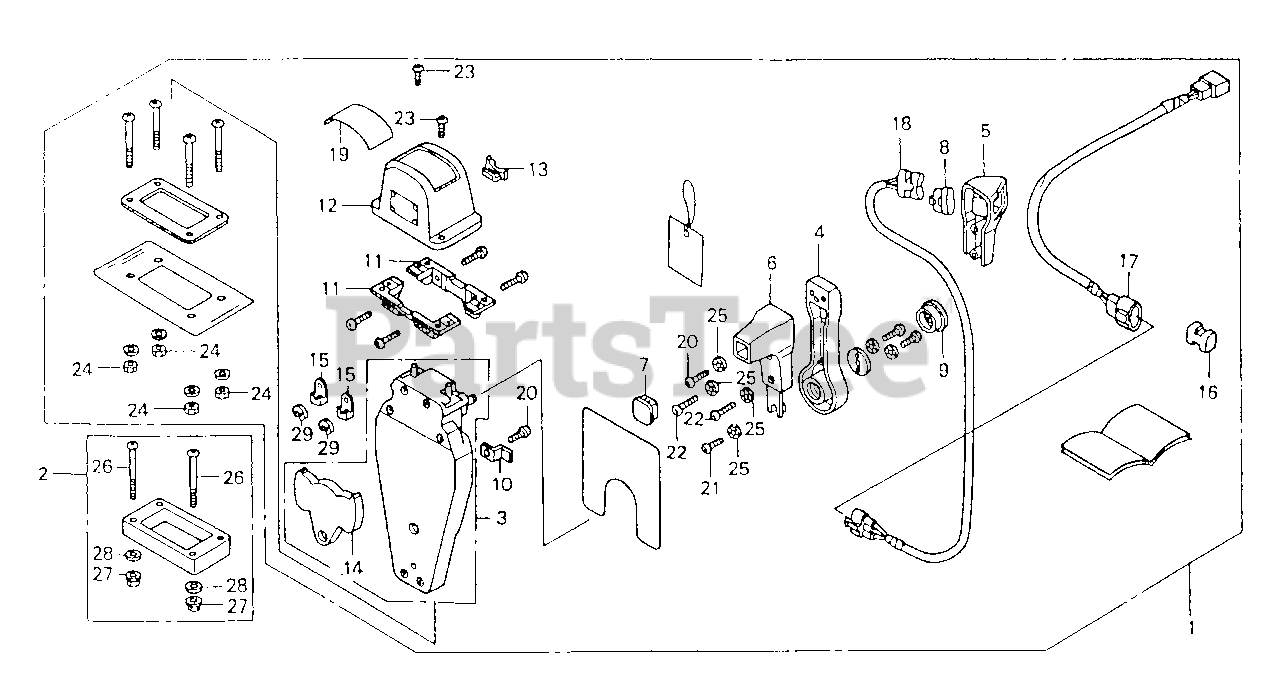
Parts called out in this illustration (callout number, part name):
1	BOX KIT, L. REMOTE CONTROL (TOP MOUNT SINGLE)
2	SPACER, TOP SINGLE
3	HOUSING ASSY., R. (INNER) (TOP MOUNT)
4	HANDLE, REMOTE CONTROL
5	COVER, R. GRIP
6	GRIP, REMOTE CONTROL HANDLE
7	CAP, GRIP
8	CAP, SWITCH
9	BUTTON, THROTTLE
10	PLATE, CABLE CLAMP
11	BRACKET, REMOTE CONTROL HOUSING
12	HOUSING, REMOTE CONTROL BOX
13	HOUSING, LEAD
14	PLATE, DWELL
15	CABLE, TERMINAL
16	SPACER, CABLE CLAMP
17	SUB-HARNESS B ASSY., POWER TRIM-TILT
18	SWITCH ASSY., POWER TRIM-TILT
19	MARK, REMOTE CONTROL TOP MOUNT SINGLE
19	MARK, REMOTE CONTROL (SINGLE)
20	SCREW, PAN (5X16)
21	SCREW, PAN (5X10)
22	SCREW, PAN (5X20)
23	SCREW, PAN (4X10)
24	NUT, HEX. (5MM)
25	WASHER, LOCK (5MM)
26	SCREW, PAN (5X65)
27	NUT, FLANGE (5MM)
28	WASHER, PLAIN (5MM)
29	E-RING (6MM)
